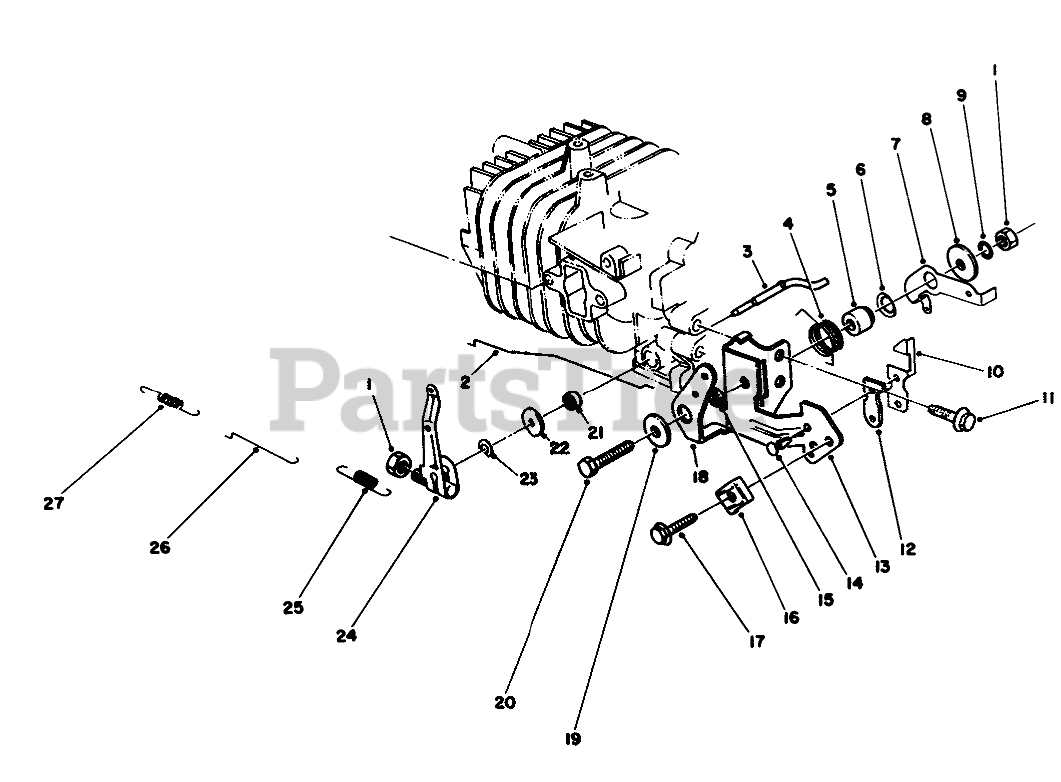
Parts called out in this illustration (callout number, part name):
2	CHOKE ROD
3	Shaft-Govemor
4	SPRING-CHOKE LEVER
5	Gov Lever Spacer
6	Washer-Gov. Spring Lever
7	LEVER-SPRING, GOVERNOR
8	WASHER
9	LOCKWASHER
10	TERMINAL-KILL SWITCH
12	INSULATOR-KILL SWITCH
13	BRACKET-THROTTLE, CONTROL
14	KILL SWITCH RIVET
15	SPACER-CHOKE LEVER
16	CLAMP
18	LEVER-CONTROL, CHOKE
19	WASHER
21	SEAL-OIL
22	WASHER
23	E-RING
24	Governor Arm/Bolt Assembly
25	SPRING-GOVERNOR
26	ROD-CARBURETOR
27	SPRING
